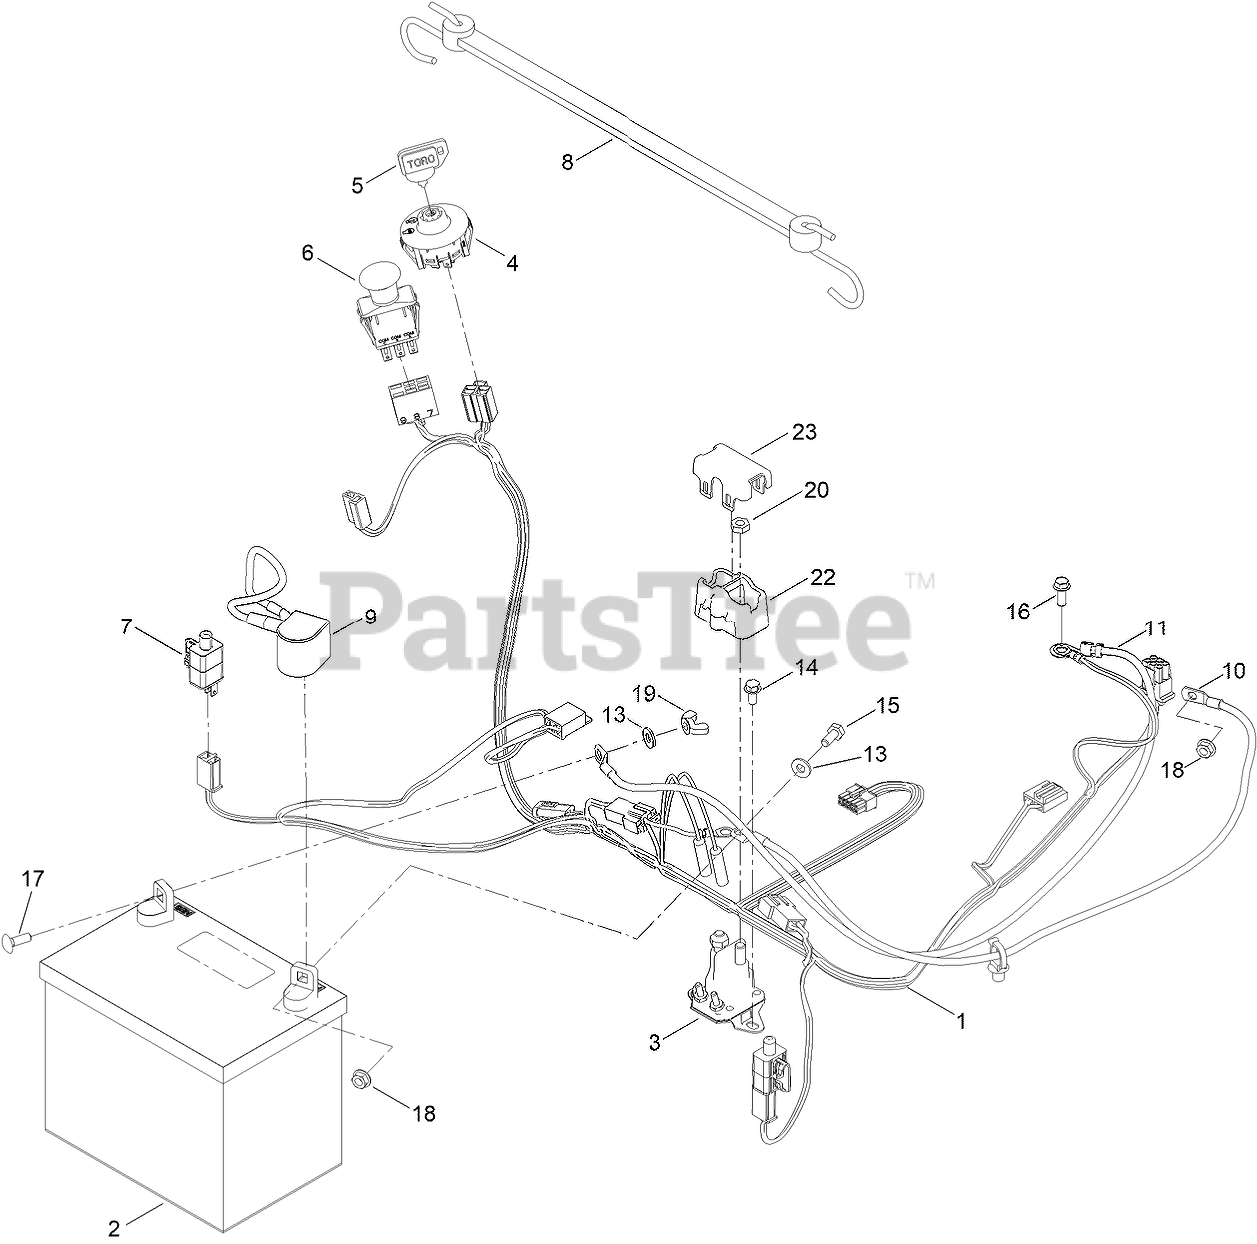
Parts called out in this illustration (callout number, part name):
1	HARNESS-WIRE
2	BATTERY
3	SOLENOID
4	SWITCH-IGNITION
5	KEY-IGNITION
6	SWITCH-PTO
7	SWITCH
8	STRAP-RUBBER
9	CABLE-BATTERY, POS
10	CABLE-BATTERY, RED (8 GAUGE)
11	CABLE-BATTERY, BLACK
13	WASHER-FLAT
14	SCREW-HWH
15	SCREW-HH
16	SCREW-HWH
17	BOLT-CARR
18	NUT-HF
19	NUT-WING
20	NUT-JAM
22	COVER-SOLENOID
23	CAP-SOLENOID
